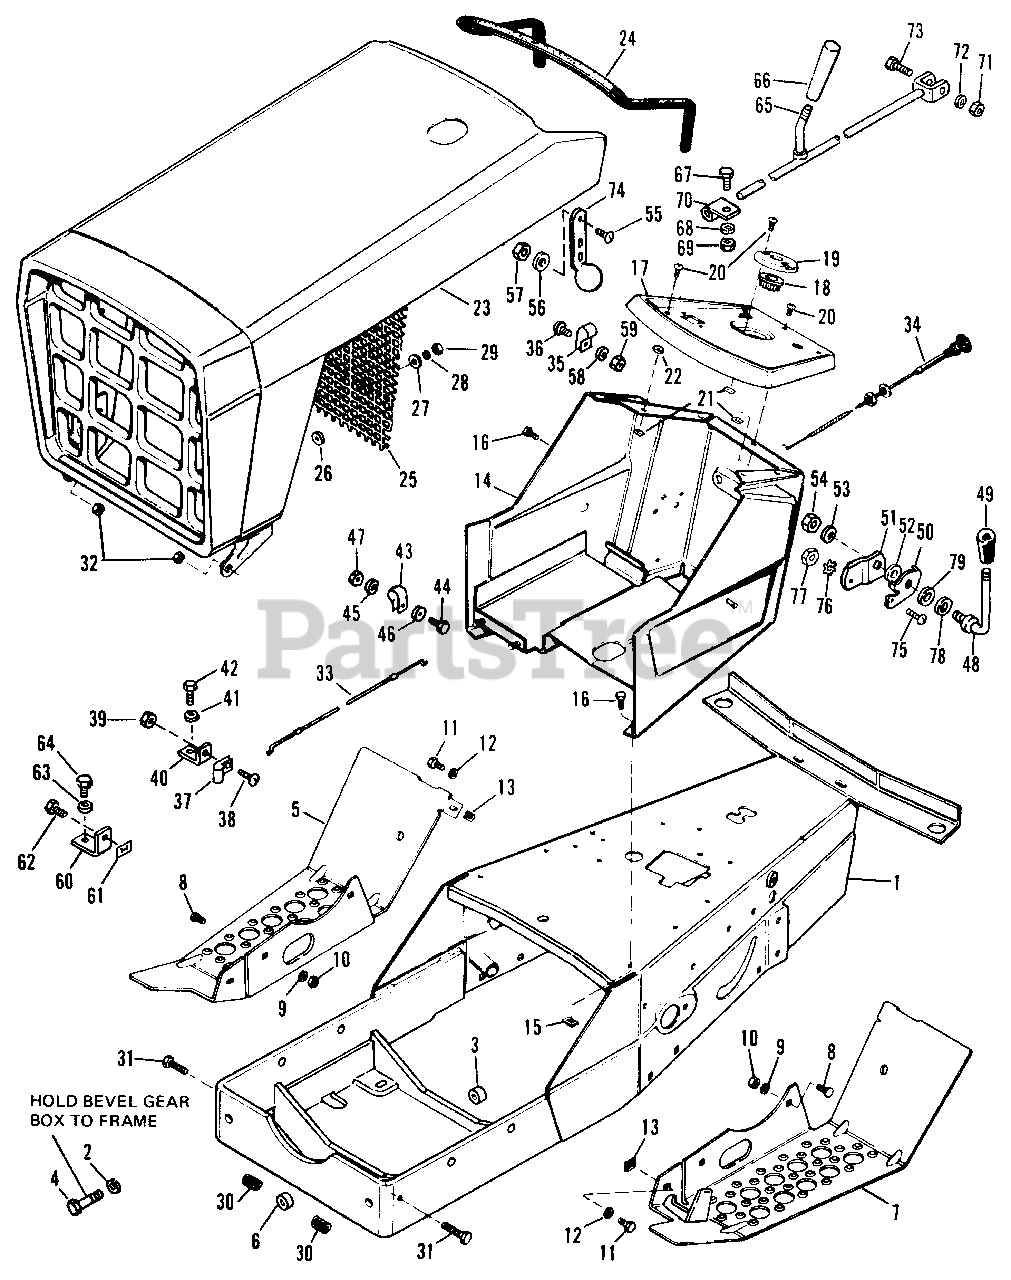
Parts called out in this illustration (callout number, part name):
1	Frame Assembly
2	Lockwasher, 7/16"
4	Hex Capscrew, 7/16"-14 N.C. x 1-1/2"
5	Foot Rest, R.H.
7	Foot Rest, L.H.
8	Carriage Bolt, 5/16"-16 N.C. x 3/4"
9	Lockwasher, 5/16"
10	Full Hex Nut, 5/16"-18 N.C.
11	Hex Capscrew, 5/16"-18 N.C. x 3/4"
12	Lockwasher, 5/16"
13	Nut, Tinnerman, 5/16"-18 N.C.
14	Dash Assembly
15	Nut, Tinnerman
16	Hex Head Self Tapping Screw, No. 14 AB x 3/4"
17	Panel, Instrument
18	Bushing, Steering
19	Plate, Steering Adj.
20	Round Head Phillips Screw, 1/4"-20 N.C. x 1/2"
21	Nut, Tinnerman, 1/4"-20 N.C.
22	Plain Washer
23	Grille & Hood Assembly
24	Molding, Hood
25	Screen, Grille
28	Lockwasher, Shakeproof No. 10
29	Full Hex Nut, No. 10-24 N.F.
31	Hex Capscrew, 3/8"-16 N.C. x 1-1/2"
32	Hex Lock Nut, Center, 3/8"-16 N.C.
33	Throttle Control
34	Choke Control
35	Clip, Bowden Wire
36	Self Tapping Rd. Hd. Screw, No. 10-24 N.C. x 1/2"
37	Clip, Bowden Wire
38	Rd. Hd. Machine Screw, No. 10-32 N.F. x 3/8"
39	Full Hex Nut. No. 10-32 N.F.
40	Bracket, Throttle Cable
41	Lockwasher, 1/4"
42	Self Tapping Rec. Hex Hd. Screw, 1/4"-20 N.C. x 5/8"
44	Hex Capscrew, 1/4"-20 N.C. x 5/8"
45	Lockwasher, 1/4"
46	Plain Washer, 1/4" Std.
47	Full Hex Nut, 1/4"-20 N.C.
48	Throttle Handle
49	Knob
50	Stop Throttle
51	Arm Throttle
53	Washer Lock Dished Type, 3/8"
54	Full Lock Hex Nut, 3/8"-16 N.C.
55	Phillips Truss Head Screw, No. 10-32 x 1/2"
57	Gripco Lock Nut, No. 10-32
58	Lockwasher, No. 12
59	Full Hex Nut, No. 10-24
60	* Bracket, Pulley Guard
61	* Nut, Tinnerman
62	* Hex Capscrew, 1/4"-20 x 3/4"
63	* Plain Washer, 3/16"
64	* Hex Head Screw, No. 14 x 1-1/4"
65	Shifter Rod Assembly
67	Hex Capscrew, 5/16"-18 x 1-1/2"
68	Lockwasher, 5/16"
69	Full Hex Nut, 5/16"-18
70	Shift Rod Guide Assembly
71	Full Hex Nut, 1/4"-20
72	Lockwasher, 1/4"
73	Hex Capscrew, 1/4"-20 x 5/8"
75	Round Head Machine Screw, No. 10-32 x 1/2"
76	Lockwasher, Shakeproof No. 10
77	Full Hex Nut, No. 10-32
